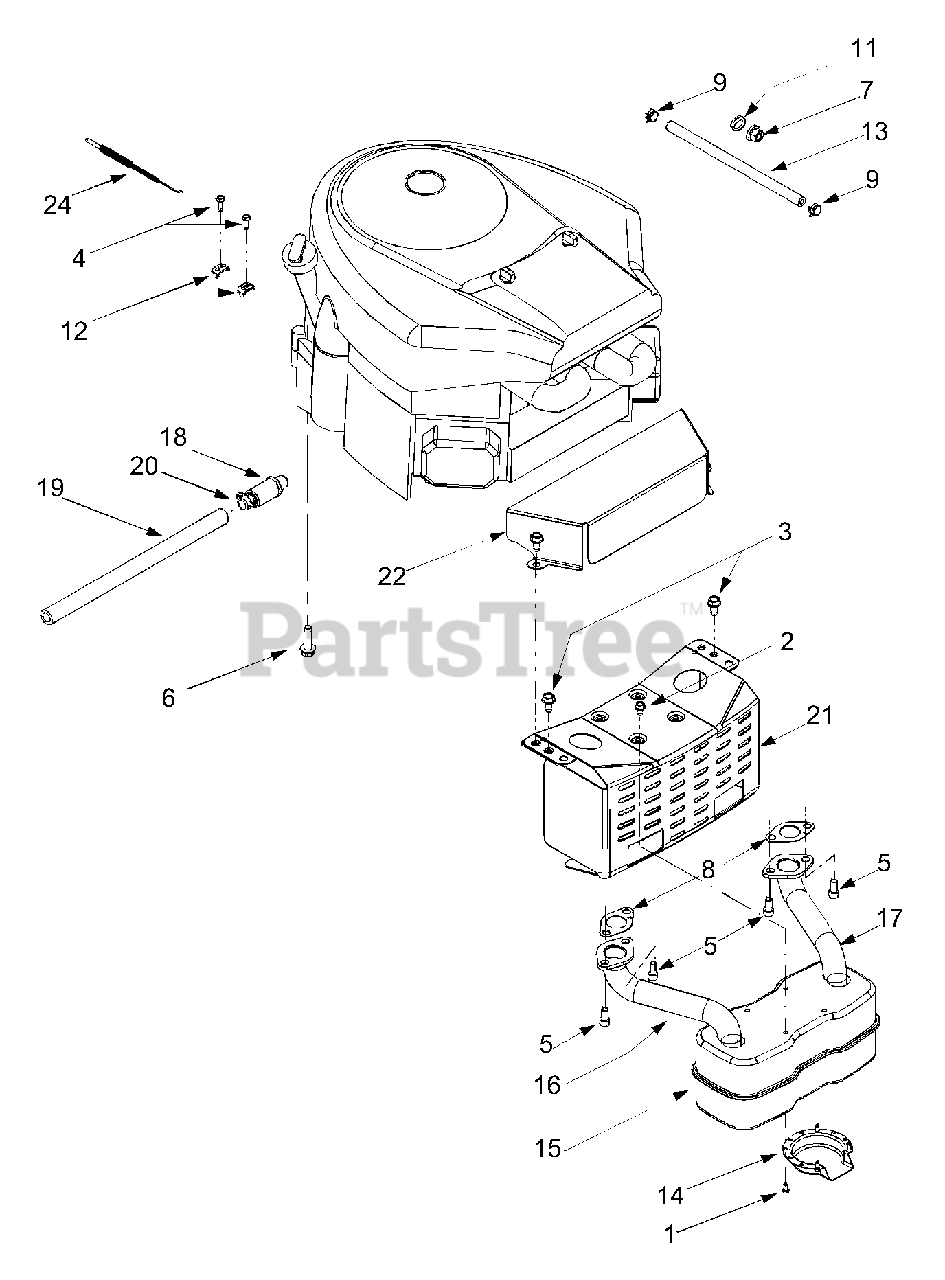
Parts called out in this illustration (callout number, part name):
1	Self-tapping Screw, #8-18 x .5
2	Self-tapping Screw, 1/4-20 x .5
3	Self-tapping Screw, 5/16-18 x .625
4	Screw, #10-32 x .625
5	Socket Cap Screw, 5/16-18 x .625
6	Self-tapping Screw, 3/8-16 x 1.25
7	Hex Nut, 3/8-16
8	Exhaust Gasket
9	Hose Clamp
11	Flat Washer
12	Casing Clamp
13	Fuel Line Hose
14	Muffler Deflector
15	Muffler, Twin Inlet
16	RH Exhaust Pipe
17	LH Exhaust Pipe
18	Oil Drain Valve
19	Oil Drain Hose
20	Oil Drain Cap
22	Engine Heat Shield
24	Throttle Cable
